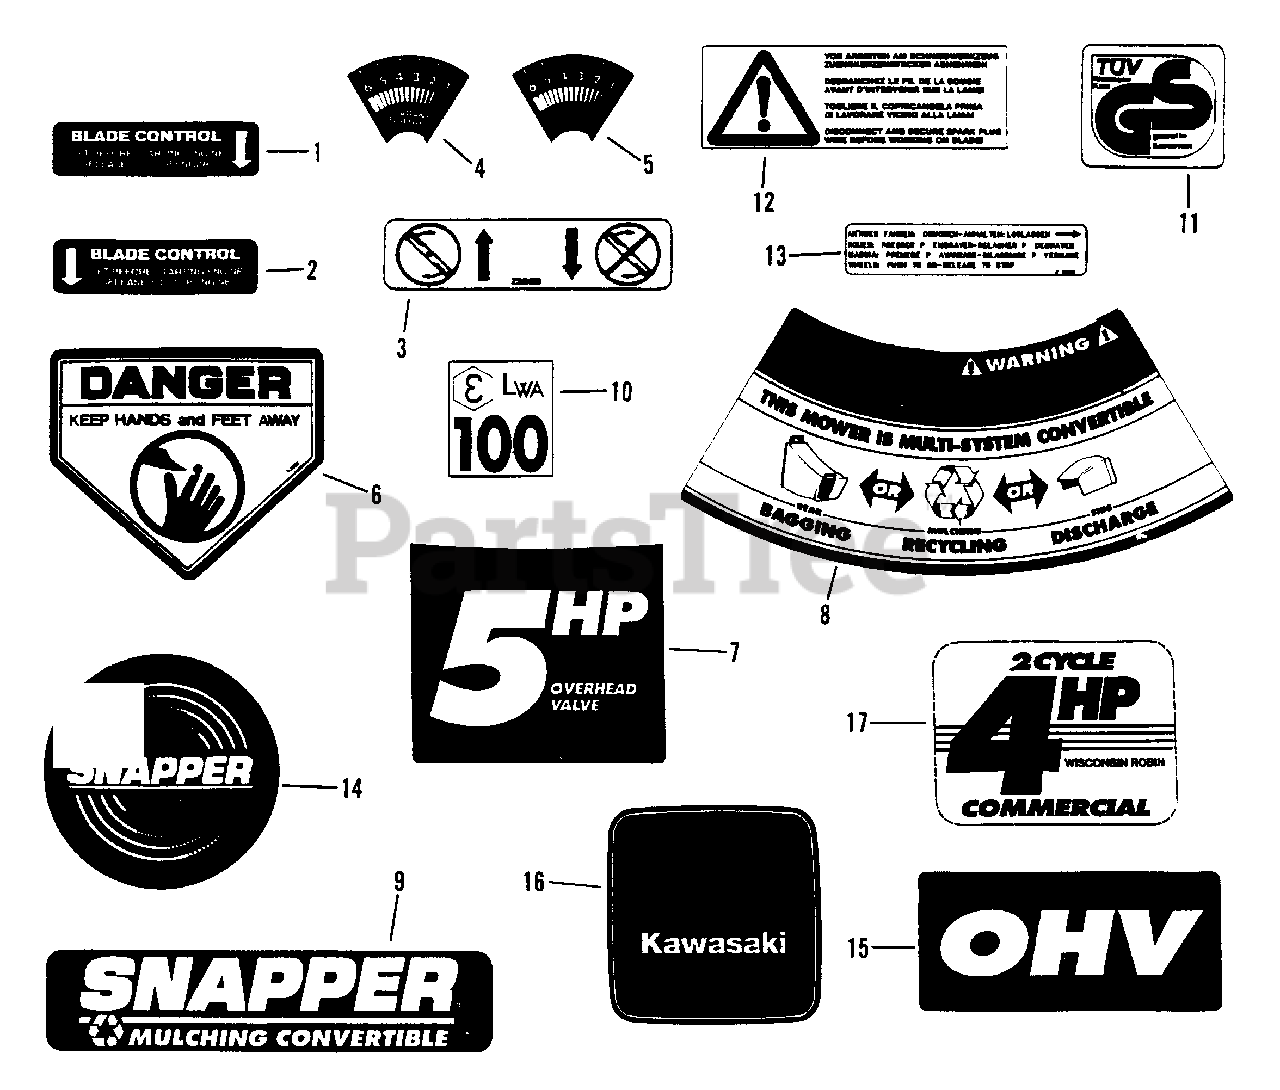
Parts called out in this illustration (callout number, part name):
1	DECAL, Blade Control
2	DECAL, Blade Control
3	DECAL, Blade Control
4	DECAL, Speed Sector
5	DECAL, Speed Sector
6	DECAL, Danger
7	DECAL, 5 HP Overhead Valve
8	DECAL, Convertible
9	LOGO, Recycling / Mulching
10	DECAL, Noise Control
11	DECAL, GS
12	DECAL, Spark Plug
13	DECAL, Wheel Control
14	DECAL, Snapper (3.38 Dia.)
15	DECAL, OHV (Overhead Valve)
16	DECAL, Kawasaki
17	DECAL, 4 HP - 2 Cycle
